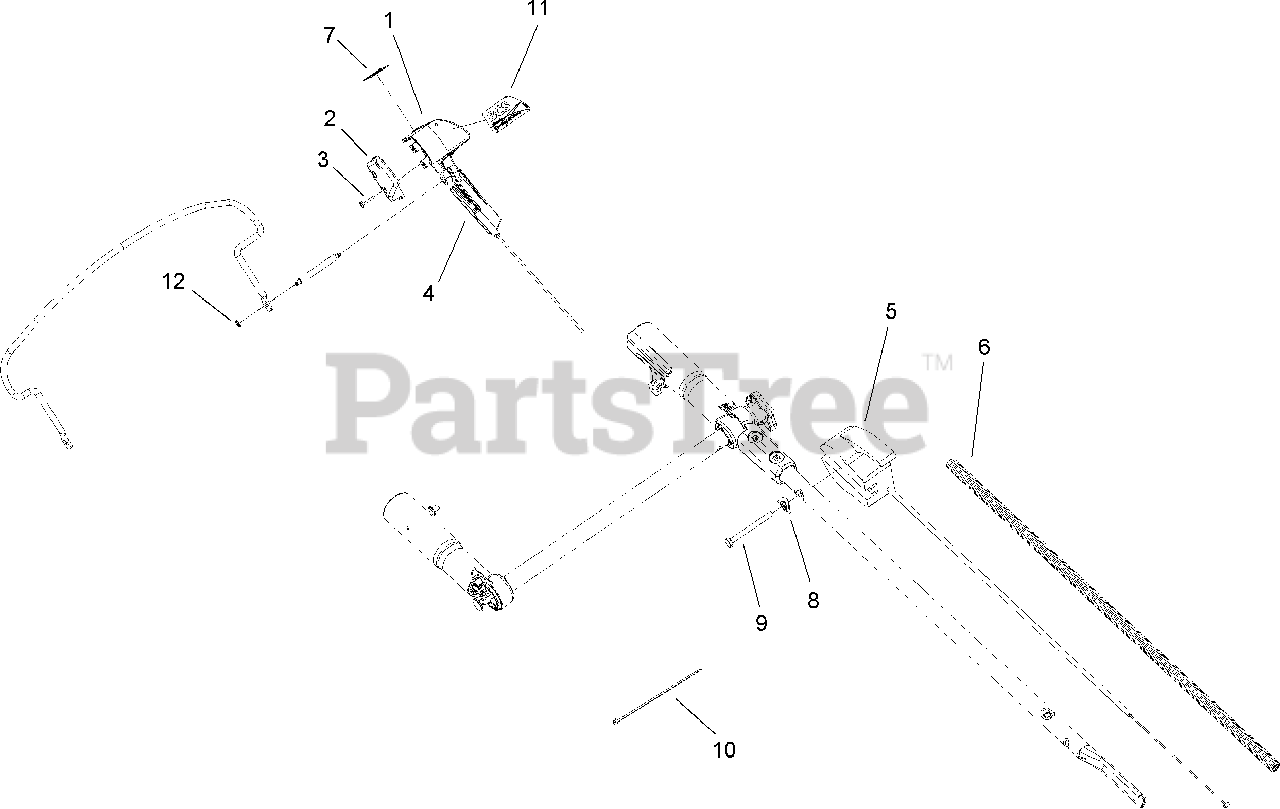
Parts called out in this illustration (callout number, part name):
1	SAFETY SWITCH ASM
2	COVER-SWITCH
3	SCREW-PPH
4	CABLE-BCS
5	CABLE-THROTTLE
7	DECAL-BLADE
9	SCREW-HH
10	STRAP-TIE
11	DECAL-CONTROL, BLADE
12	RING-RETAINING
